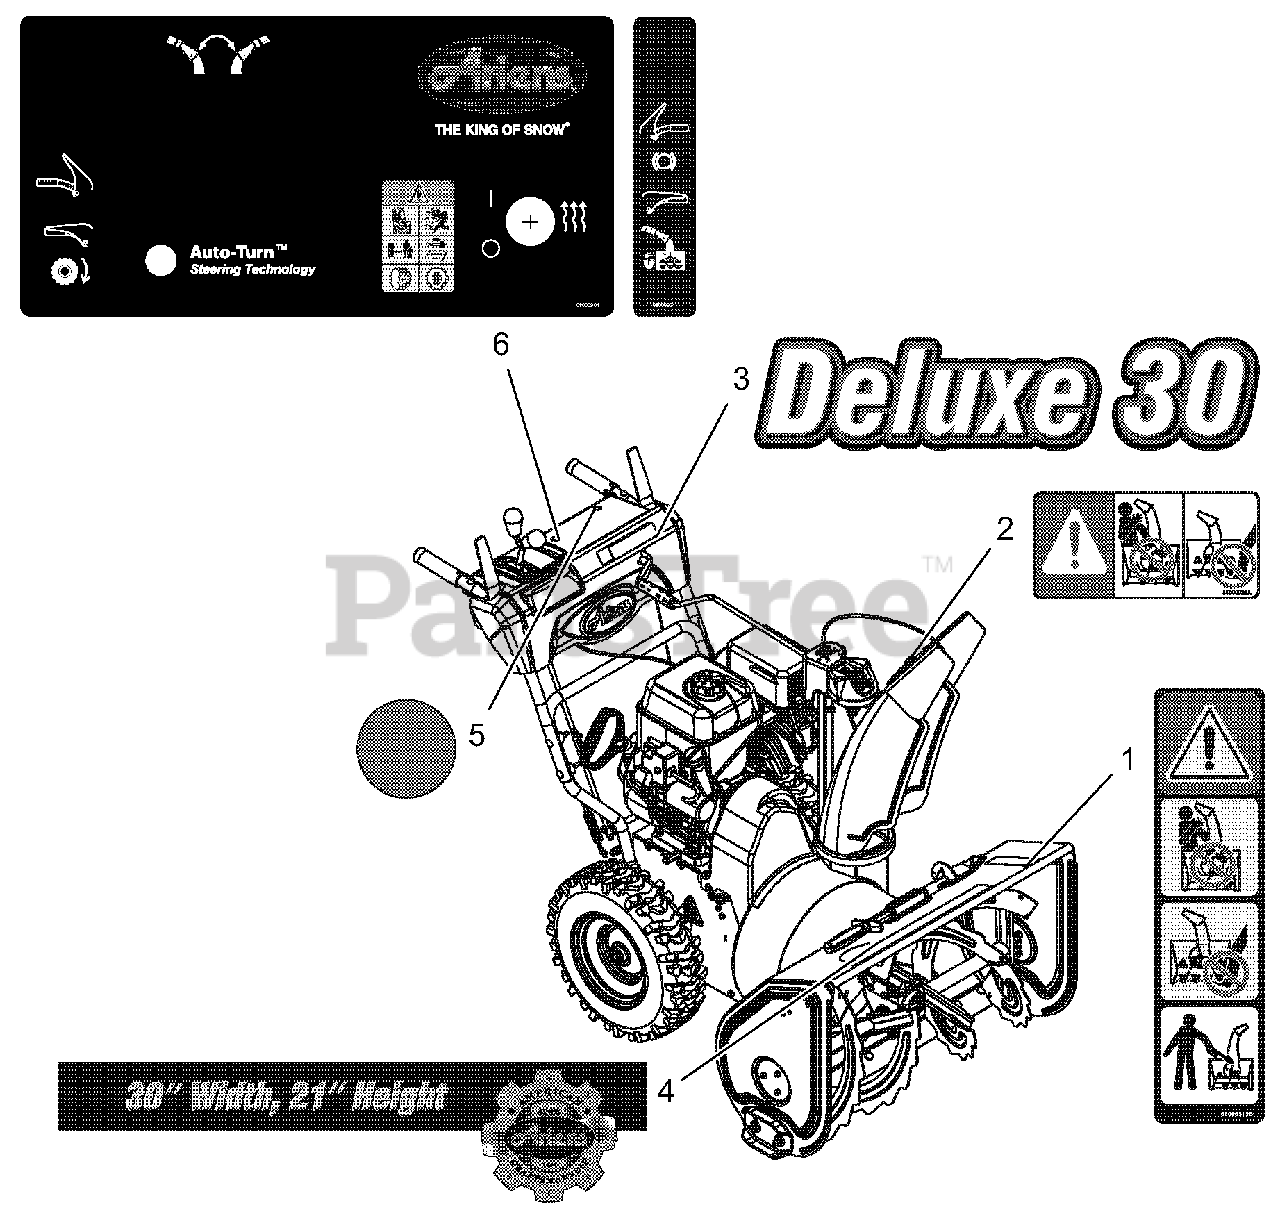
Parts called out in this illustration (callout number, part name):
1	DECAL, DANGER - ROTATING PARTS
2	DECAL, DANGER
3	DECAL, DELUXE 30
5	DECAL,AUTODIFFERENTIAL
6	DECAL, CONTROL DELUXE
